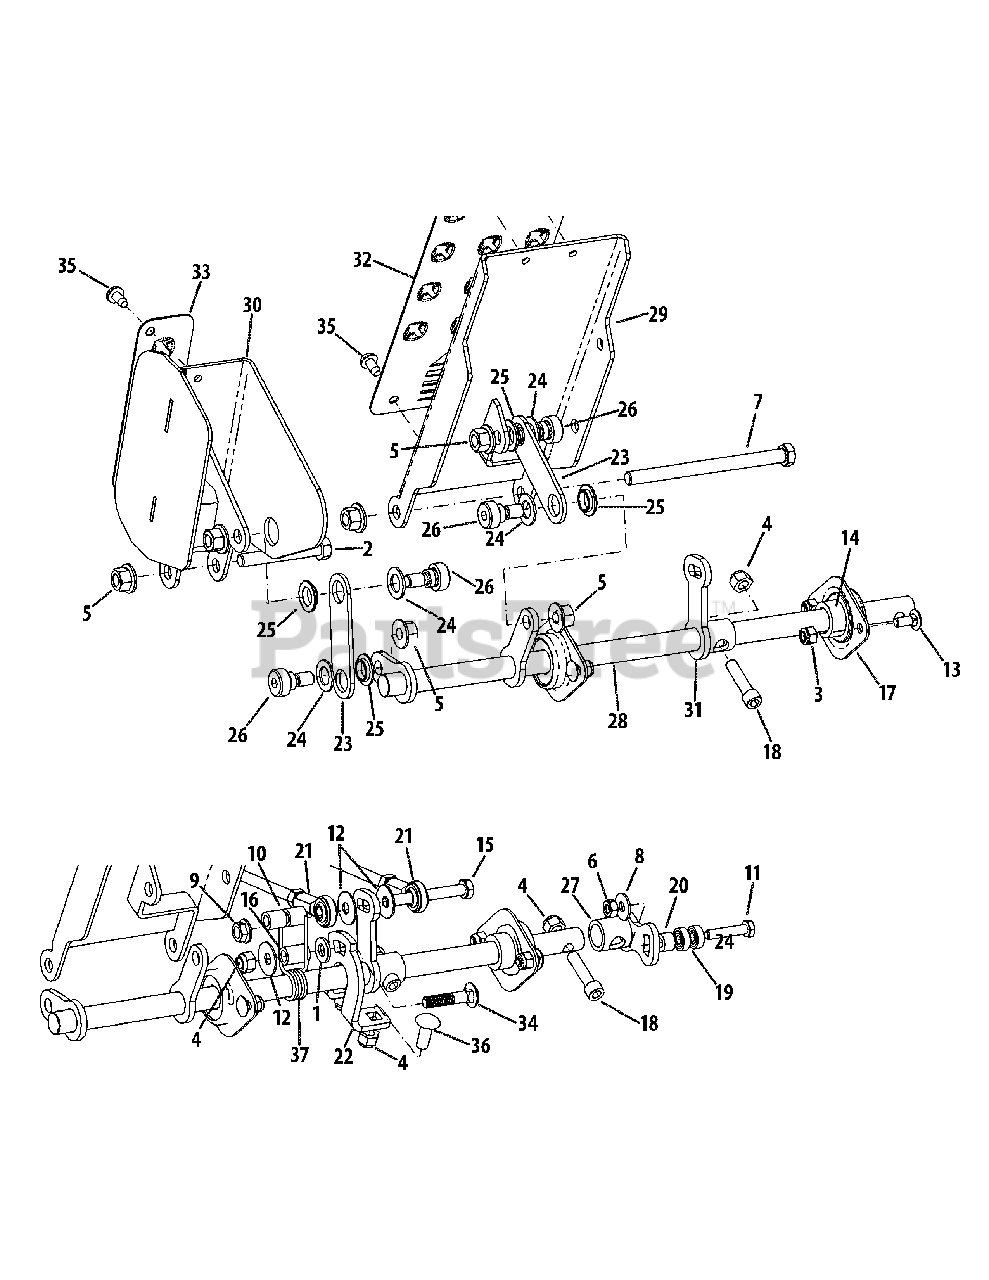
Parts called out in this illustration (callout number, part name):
1	Washer, .344 x .688 x .063
2	Hex Screw, 3/8-16 x 2.50
3	Nut, 1/4-20
4	Nut, 5/16-18
5	Flange Counter Lock Nut, 3/8-16
6	Counter Lock Nut, 1/4-20
7	Hex Screw, 3/8-16 x 5.00
8	Bell Washer, .265 x .75 x .062
9	Flange Counter Lock Nut, 5/16-18
10	Spacer, .315 x .500 x .520
11	Hex Screw, 1/4-20 x 1.25
12	Bell Washer, .325 x .930 x .045
13	Carriage Bolt, 1/4-20 x .620
14	Shaft Collar, .625 x 1.00 x .438
15	Hex Screw, 5/16-18 x 2.50
16	Spacer, .315 x .500 x .699
17	Flange Bearing
18	Screw, 5/16-18 x 1.25
19	Ball Bearing, .25 x .625 x .196
20	Spacer, .256 x .500 x .330
21	Speed Control Link Assembly
23	Pedal Control Link
24	Washer, .51 x .88 x .06
25	Flange Bearing, .502 x .875 x .180
26	Shoulder Bolt, 3/8-16 x .50 x .25
27	Lockout Hub Assembly
28	Pedal Bellcrank Assembly
29	Forward Pedal Assembly
30	Reverse Pedal Assembly
31	Control Arm Assembly
32	Forward Pedal Grip
33	Reverse Pedal Grip
34	Carriage Bolt, 5/16-18 x 1.50
35	Screw, 1/4-20 x .5
36	Carriage Bolt, 5/16-18 x .875
37	Torsion Spring, .66 x .56
